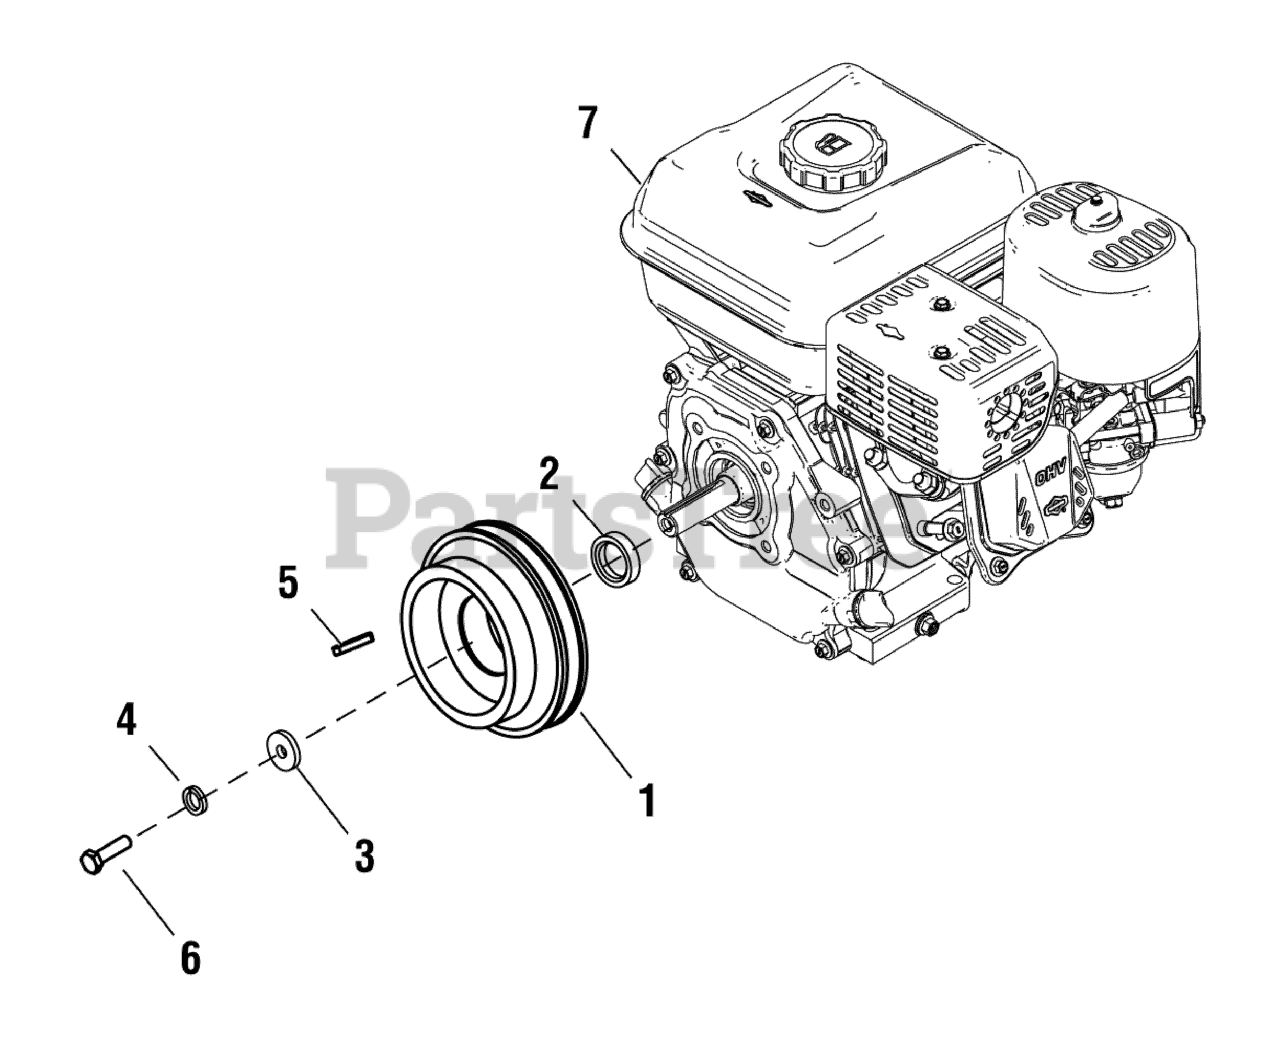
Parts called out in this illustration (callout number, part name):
1	CLUTCH
2	BUSHIING
3	KEY BUSHING
4	WASHER, Spring, 8
5	KEY 5 x 32
6	BOLT, Hex, M8 x 30
7	ENGINE
